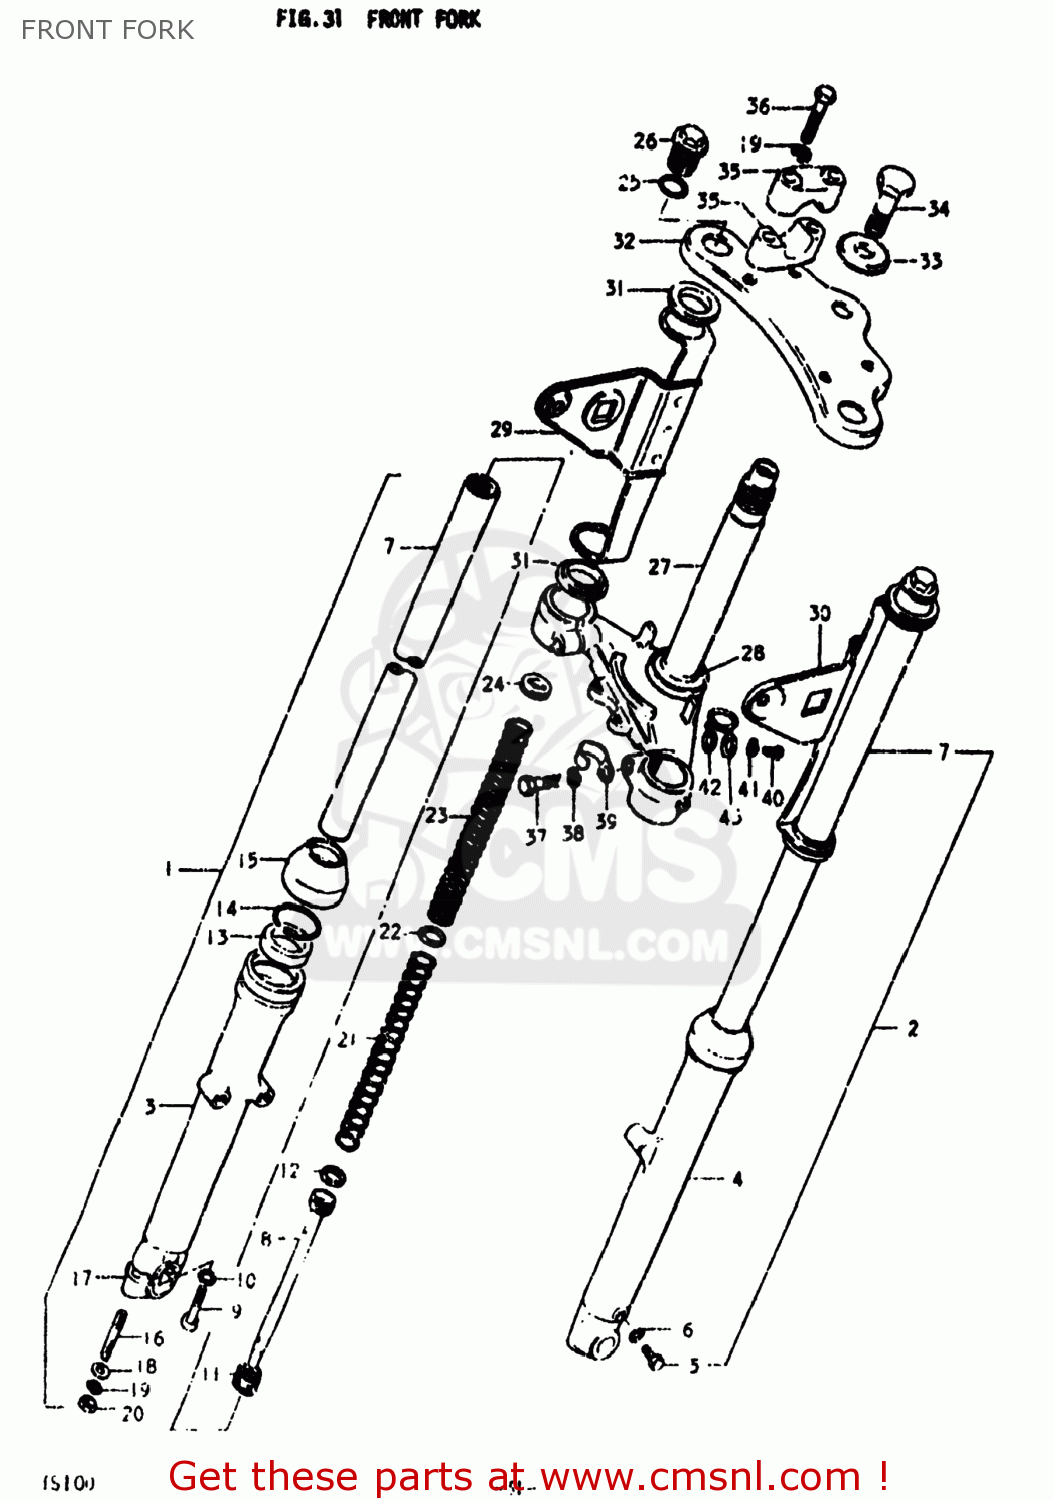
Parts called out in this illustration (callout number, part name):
1	DAMPER ASSEMBLY,RIGHT
2	DAMPER ASSEMBLY,LEFT
3	TUBE,FORK,OUTER,RIGHT
4	TUBE,FORK,LEFT,OUTER
5	BOLT(6X8)
6	GASKET,DRAIN,PLUG (NAS)
7	TUBE,FORK,INNER
8	PIPE,FORK SEAT
9	BOLT(8X27)
10	GASKET (NAS)
11	SPRING,REBOUND
12	RING,PISTON
13	OIL SEAL,FRONT FORK
14	RING,OIL SEAL STOPPER
15	DUST SEAL,FRONT FORK
16	STUD 8X25
17	HOLDER,AXLE
18	WASHER
19	LOCK WASHER
20	NUT 8MM
21	SPRING,FRONT FORK
22	JOINT,SPRING
23	SPRING,FRONT FORK
24	NUT,FORK SPRING,UPPER
25	O-RING,FORK INNER TUBE
26	CAP
27	STEM,STEERING
28	RACE,STEERING OUTER LWR
29	BRACKET,HEADLAMP,RIGHT
30	BRACKET,HEADLAMP,LEFT
31	CUSHION
32	HEAD,STEERING STEM
33	WASHER
34	BOLT,STEERING STEM HEAD
35	HOLDER,HANDLE UPR
36	BOLT 8X55
37	BOLT
38	WASHER,LOCK 12
39	CLIP
40	SCREW 6X12
41	LOCK WASHER
42	CLIP
